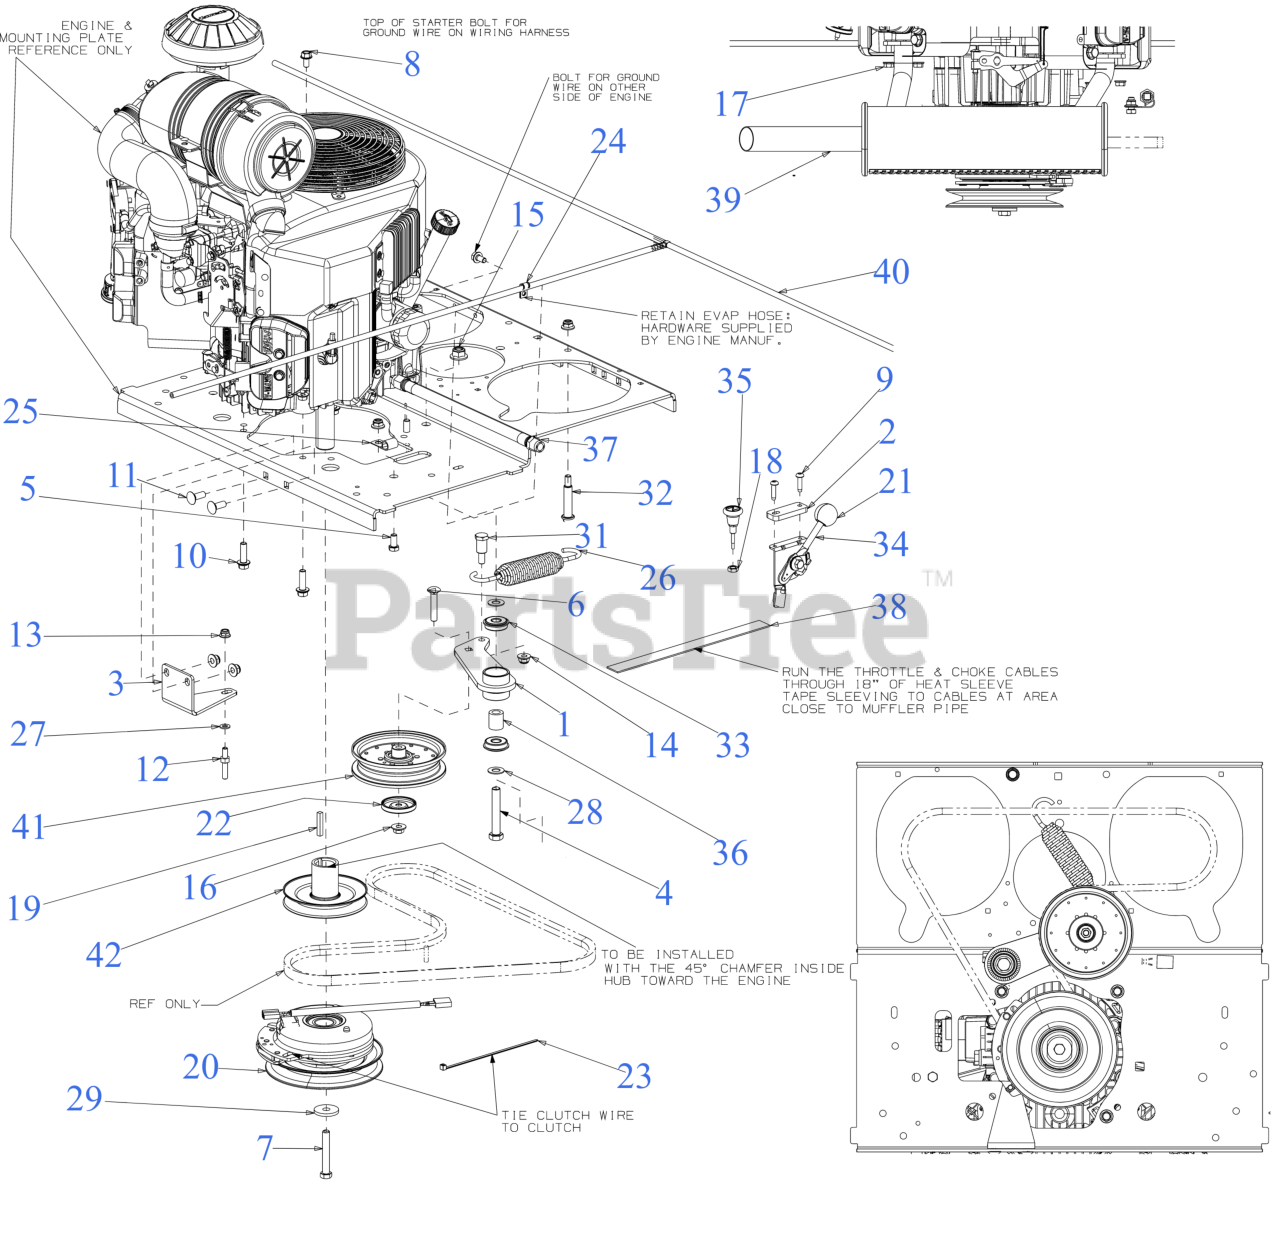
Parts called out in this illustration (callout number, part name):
1	IDLER BRACKET
3	CLUTCH RETAINER BRACKET
4	SCREW-HEX 1/2-13 x 3.00
5	HEX SCREW 3/8-16 x .75
6	CARRIAGE BOLT 3/8-16 x 2
7	SCREW 7/16-20:2.75 GR5
8	SCREW M8 x 1.25 x 16MM GR8.8
9	SCREW 1/4-20 x 1.0
10	SCREW 3/8-16 x 1.25 GR5
11	CARRIAGE BOLT 3/8-16 x 1.00 GR5
13	FLANGE LOCK NUT 5/16-18
16	FLANGE LOCK NUT
17	HEX FLANGE NUT
18	HEX JAM NUT 3/8X24
19	SQUARE KEY 1/4 x 1.50
20	ELECTRIC PTO CLUTCH
22	PULLEY CAP
23	7" CABLE TIE
24	MOUNTING CLAMP
25	J TYPE CLIP
26	EXTENSION SPRING W/HOOK
27	FLAT WASHER
28	FLAT WASHER .510 x .995
29	FLAT WASHER .45 x 1.5 x .172 HT
31	SHOULDER SCREW .625 x .875 x 3/18
32	SHOULDER BOLT (.50 X 2.0 x 3/8 -16)
33	ROLLER BEARING .5X1.37X.44
34	THROTTLE CABLE 59"
35	CHOKE CABLE
36	SPACER 0.51 x 0.88 x 1.00
37	OIL DRAIN HOSE
38	HEAT SHIELD 24"
39	KAWASAKI MUFFLER
41	FLAT IDLER PULLEY
42	ENGINE PULLEY 5.425
